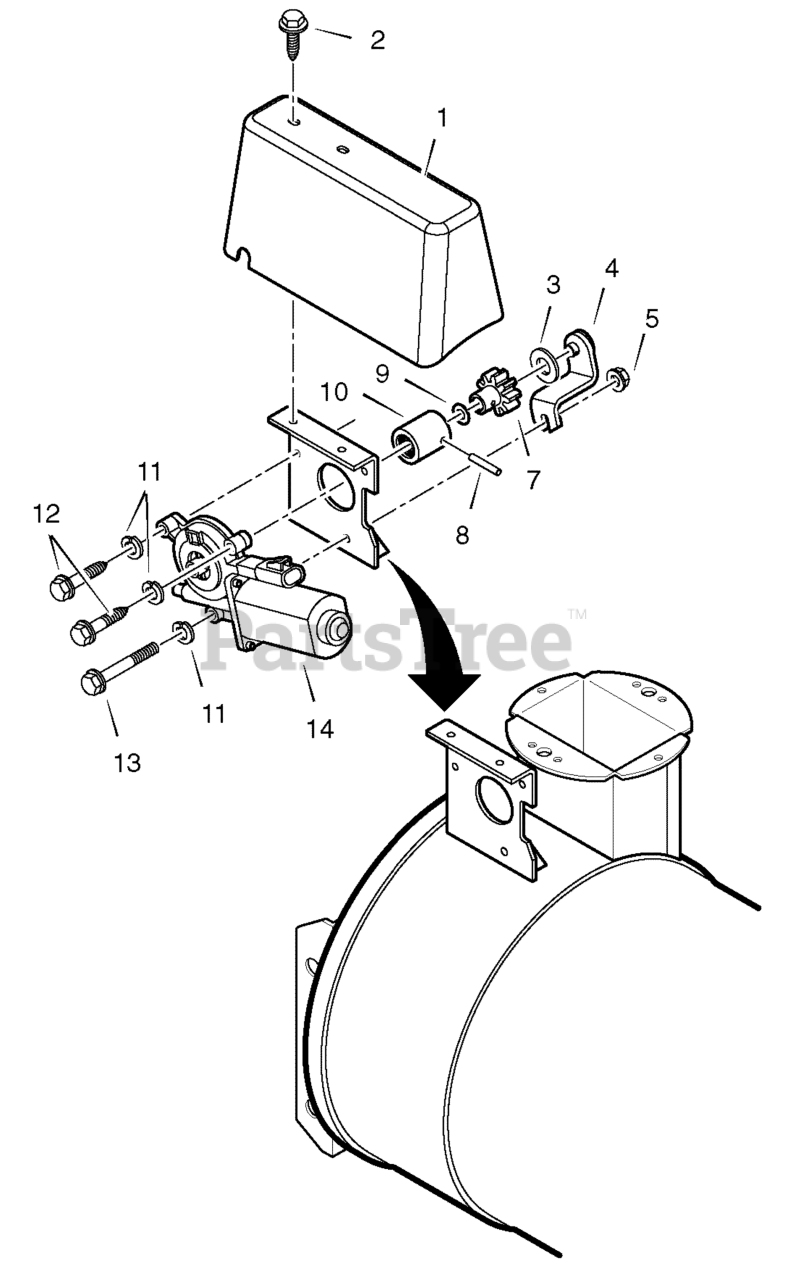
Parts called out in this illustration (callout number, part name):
1	COVER, MOTOR
4	BRACE, CHUTE GEAR
8	PIN, SPRING
9	RING, RETAINER
13	BOLT, HEX
14	MOTOR, ELECTRIC
